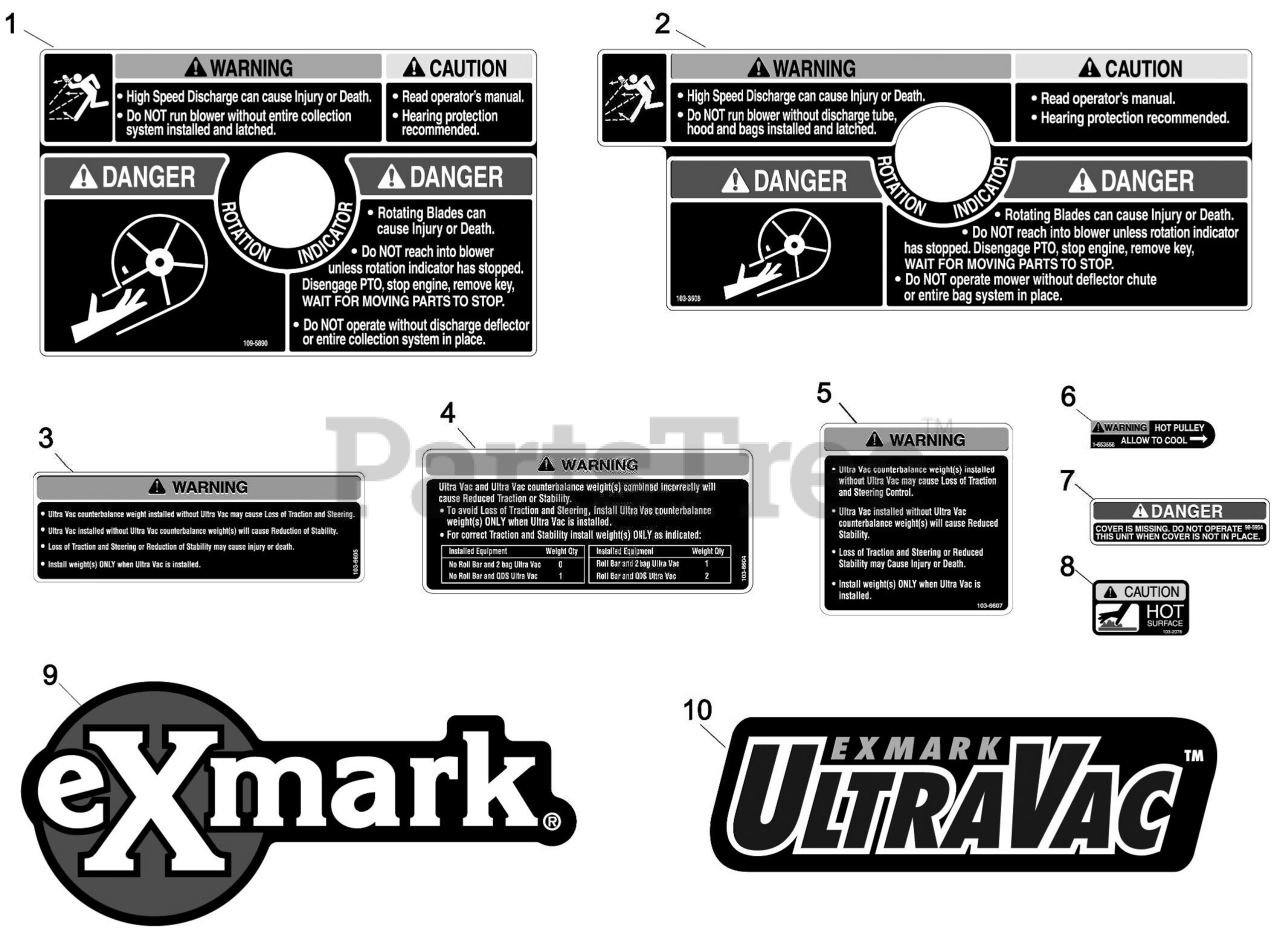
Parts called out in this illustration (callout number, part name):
1	DECAL-WARNING, BLOWER
2	DECAL-WARNING
3	DECAL,WEIGHT
4	DECAL,WEIGHT
5	DECAL,WEIGHT
6	DECAL-WARNING
7	DECAL-COVER, MISSING
8	DECAL-CAUTION
9	DECAL, EXMARK LOGO
10	DECAL, ULTRA VAC
